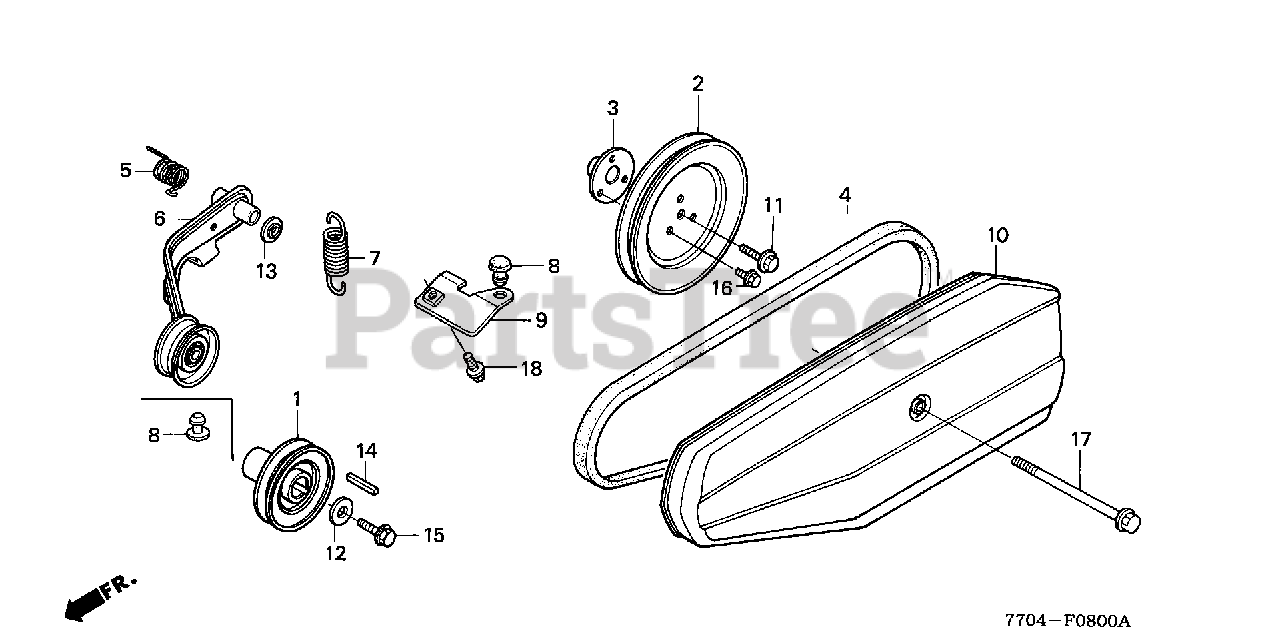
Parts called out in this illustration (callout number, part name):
1	PULLEY, DRIVE (80MM)
2	PULLEY, DRIVEN (156MM)
3	BOSS, DRIVEN PULLEY
4	V-BELT (40)
5	SPRING, TENSION ARM RETURN
6	ARM, TENSION
7	SPRING, BELT TENSIONER
8	RUBBER, TENSIONER ARM
9	STOPPER, TENSIONER ARM
10	COVER, BELT *R280* (POWER RED)
11	BOLT, FLANGE
12	WASHER (8MM)
13	WASHER, NUMBER BRACKET MOUNTING
14	KEY (5X5X33)
15	BOLT, FLANGE (8X25)
16	BOLT, FLANGE (6X10)
17	BOLT, FLANGE (6X75)
18	BOLT, FLANGE (8X12)
